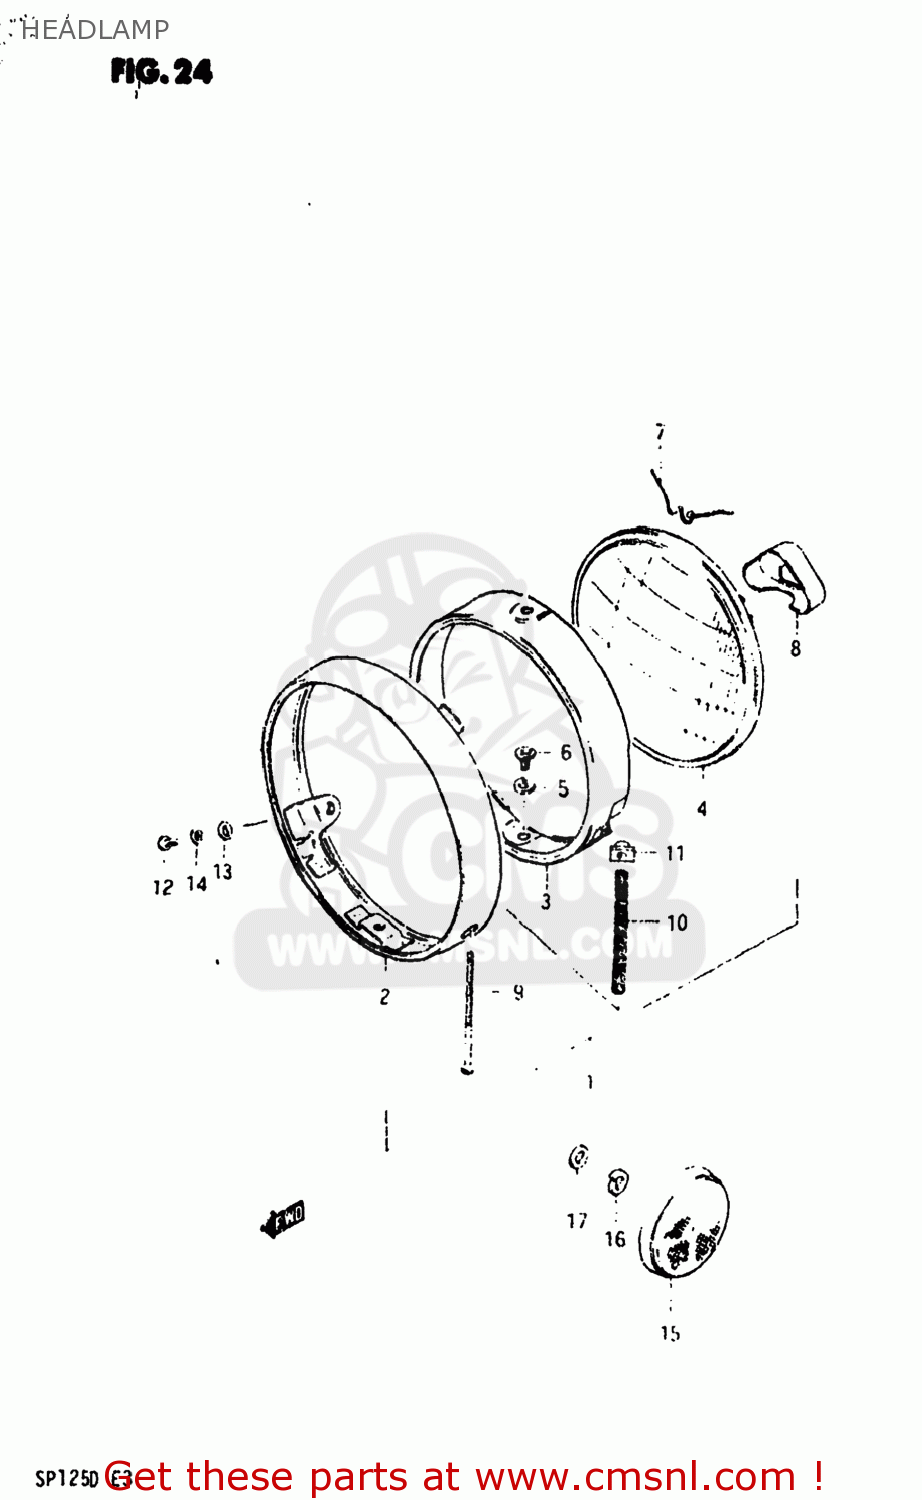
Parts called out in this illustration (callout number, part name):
1	HEADLAMP ASSEMBLY
2	RIM,HEADLAMP
3	RETAINER
4	LAMP UNIT
5	LOCK WASHER
6	SCREW
7	SPRING,HEAD LAMP UNIT
8	COVER
9	SCREW
10	SPRING
11	NUT
12	SCREW
13	WASHER
14	LOCK WASHER
15	REFLEX REFLECTOR,FR
16	LOCK WASHER
17	WASHER
